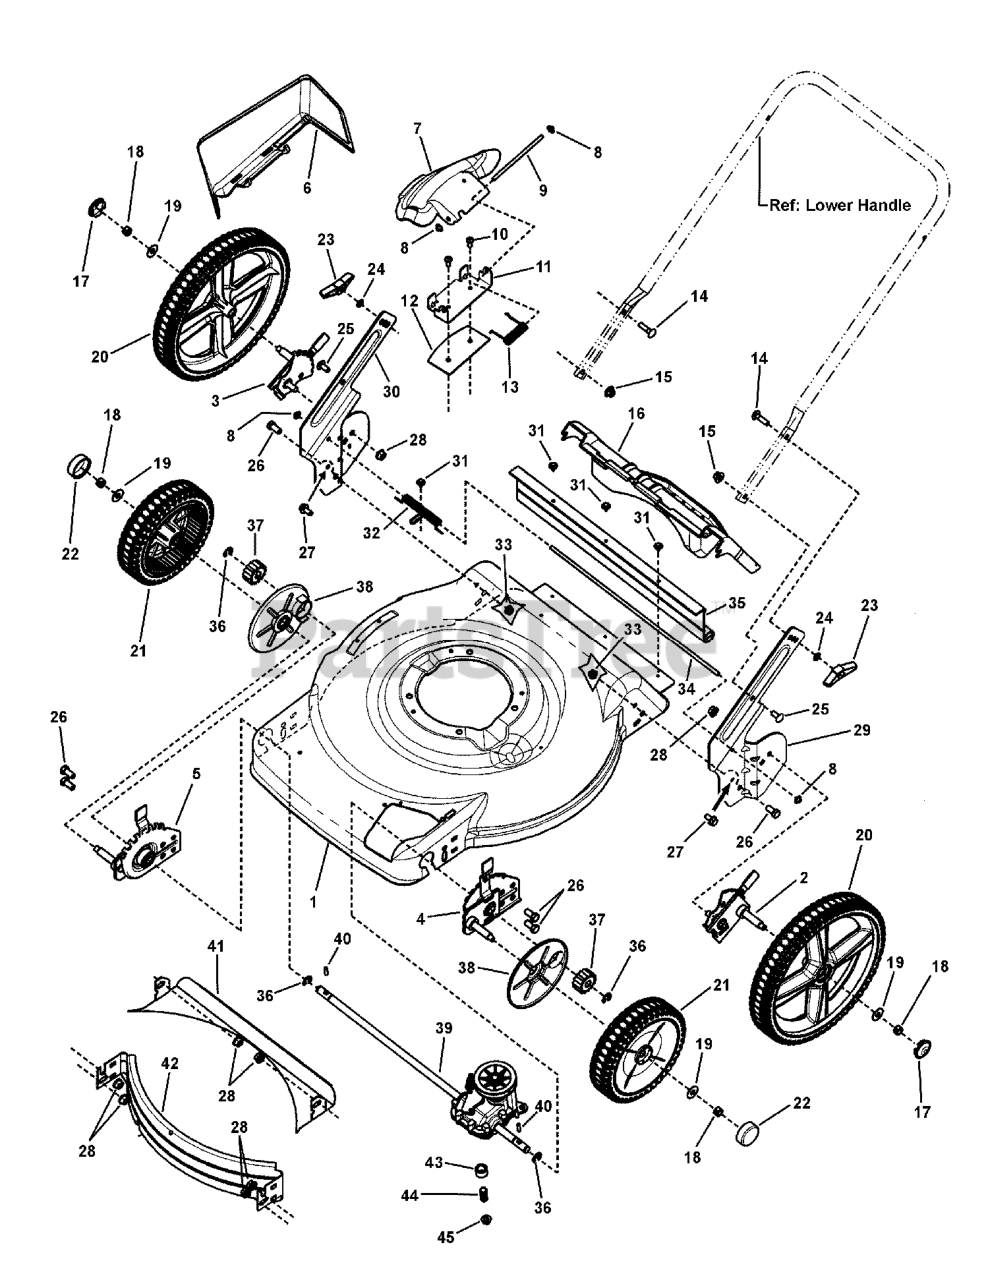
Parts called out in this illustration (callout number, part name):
1	DECK, 22" Walk, 3-N-1
2	ASSY, Height-of-Cut, Left Rear, Murray 7 Position
3	ASSY, Height-of-Cut, Right Rear, Murray 7 Position
4	ASSY, Height-of-Cut, Left Front, 22" WBM, Self-Prop, 7 Position
5	ASSY, Height-of-Cut, Right Front, 22" WBM, Self-Prop, 7 Position
6	SIDE CHUTE, Plastic, Black
7	COVER, Mulch, Plastic, Black
8	PUSHNUT, 1/4"
9	ROD, Chute Pivot (1/4" Dia. x 5.55")
10	SCREW, 1/4-20 x .550 Pan Head Self-Tap (Torx)
11	BRACKET, Chute
12	PLATE, Mulch, 22" RB Scott's
13	SPRING, Chute (Torsion)
14	BOLT, 5/16-18 x 1" Square Neck Carriage
15	NUT, 5/16-18 Large Flange Center Lock
16	DOOR, Rear Discharge, 22" Walk Mower
17	HUBCAP, 12" Wheel, Black
18	NUT, 3/8-16 Hex Center Lock, YZ
19	WASHER, 1" O.D. x .387 I.D. Flat
20	ASSY, Wheel, 12" x 2" Idle, NB, Murray Tread, Pewter
21	ASSY, Wheel, 8" x 2" Drive, NB, Murray Tread, Pewter
22	HUBCAP, Round, Black
23	KNOB, 5/16-18 Wing (Black)
24	WASHER, 5/16" Internal Tooth Lock
25	BOLT 5/16-18 x 3/4" Round Head Short Square Neck
26	SCREW, 3/8-16 x 3/4" Hex Head Cap, GR 5
27	BOLT, 5/16-18 x 5/8" Hex Flange Lock
28	NUT, 3/8-16 Hex Flange Lock, GR 5
29	BRACKET, Lower Handle, LH, 22" WBM, Hi-Wheel
30	BRACKET, Lower Handle, RH, 22" WBM, Hi-Wheel
31	SCREW, #10-24 x 1/2" Hex Washer Self-Tap (Sems)
32	SPRING, Torsion, Rear Door, 22" Walk Mower
33	NUT, 5/16-18 Flange Lock
34	ROD, Pivot, Rear Door (1/4" Dia. X 17-1/2")
35	GUARD, Rear 22" Hi-Wheel
36	RING, External Retaining
37	GEAR, Pinion, 22" WBM, FWD
38	SHIELD, Dust, 22" WBM, FWD
39	TRANSMISSION, 22" WBM Single Speed, Front Wheel Drive
40	DRIVE PIN, 22" WBM, Front Wheel Drive
41	BAFFLE, Rear, 22" Deck
42	BAFFLE, Front, 22" WBM
43	SPACER, Drive Transmission
44	SPRING, Compression
45	NUT, 5/16-18 Hex Flange Lock
